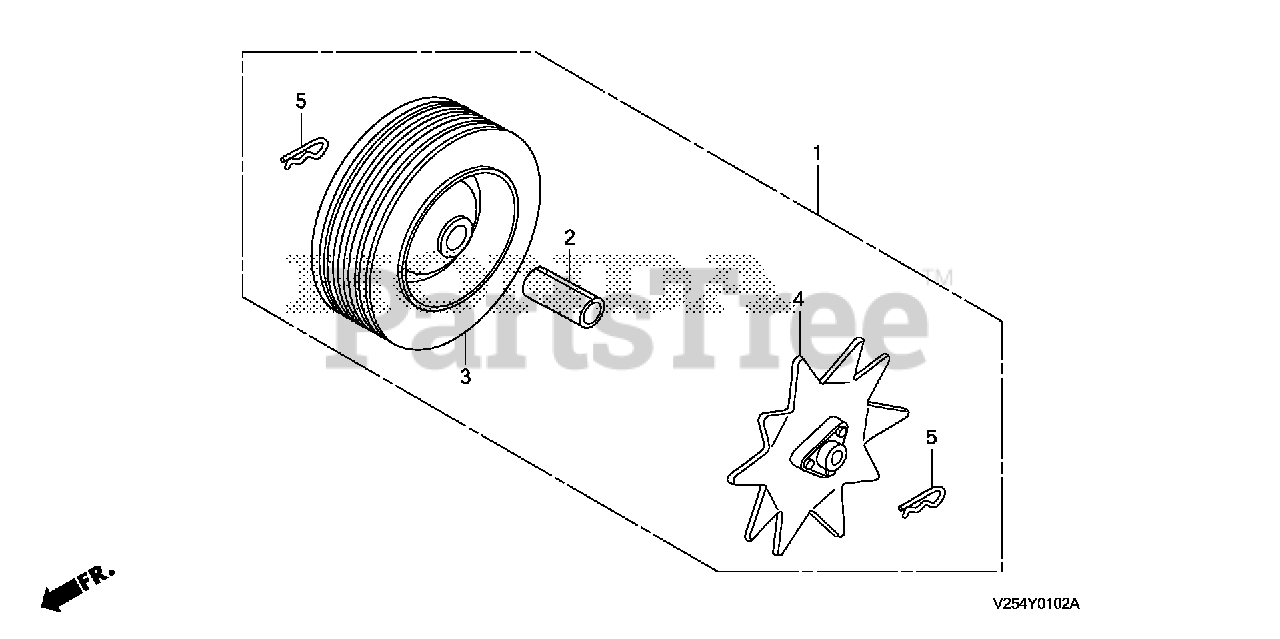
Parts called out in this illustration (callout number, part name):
1	EDGER KIT
2	SPACER (17X36) (NOT AVAILABLE)
3	WHEEL
4	TINE, EDGER
5	PIN, LOCK (17MM)
